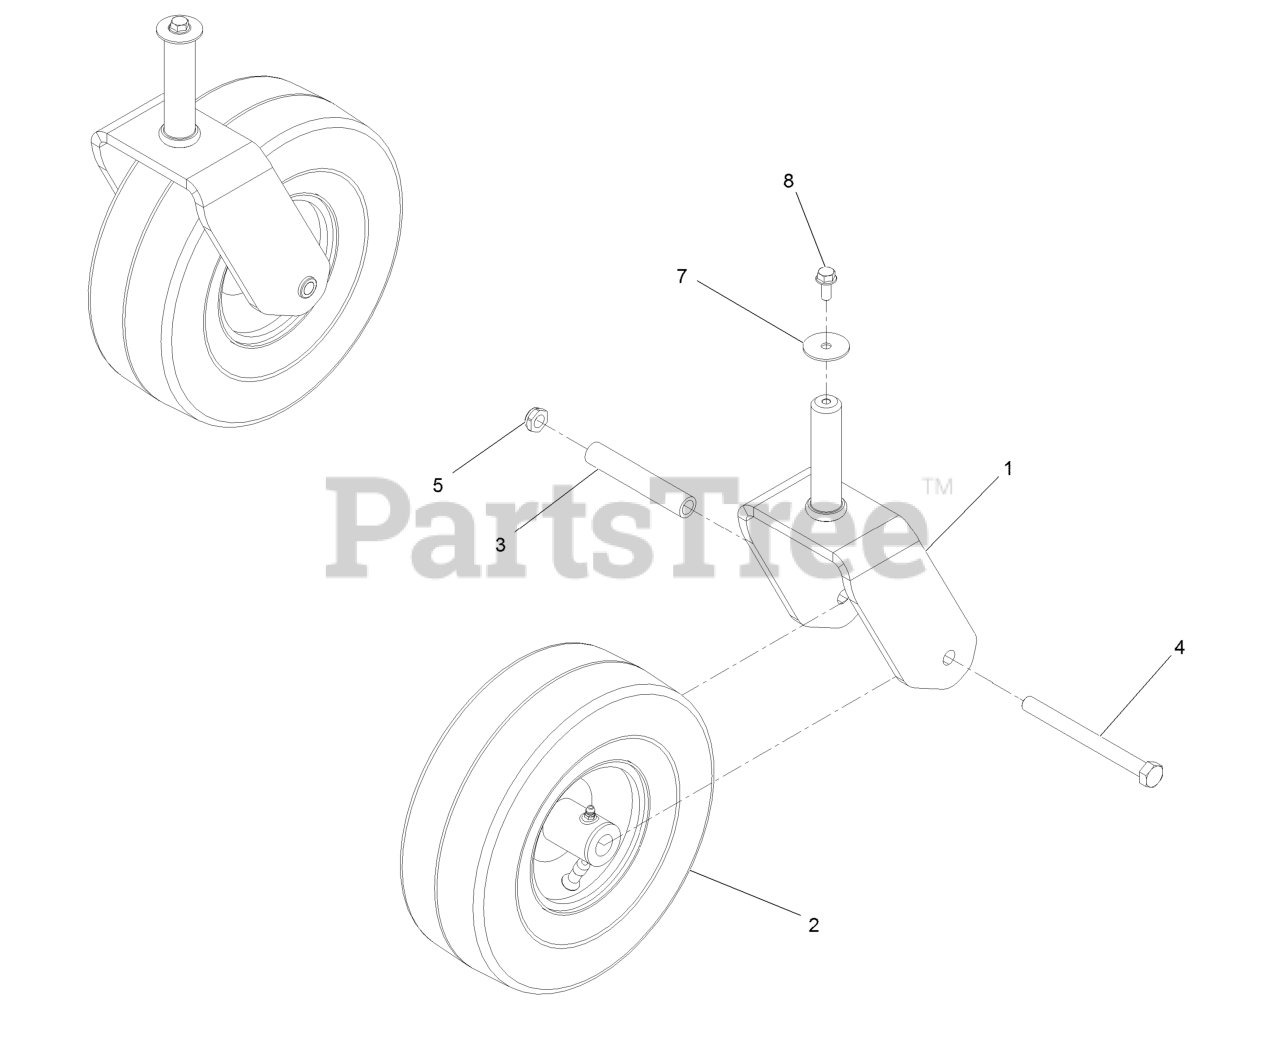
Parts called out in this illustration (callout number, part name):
1	Fork-Caster [red]
2	Tire And Wheel ASM (C S T)
3	Bushing-Spanner
4	Screw-HH 1/2-13 X 5 1/2
5	Nut-Nyloc 1/2-13 Thin
7	Washer-Flat
8	Screw-HH Flg 5/16-18 X 3/4
